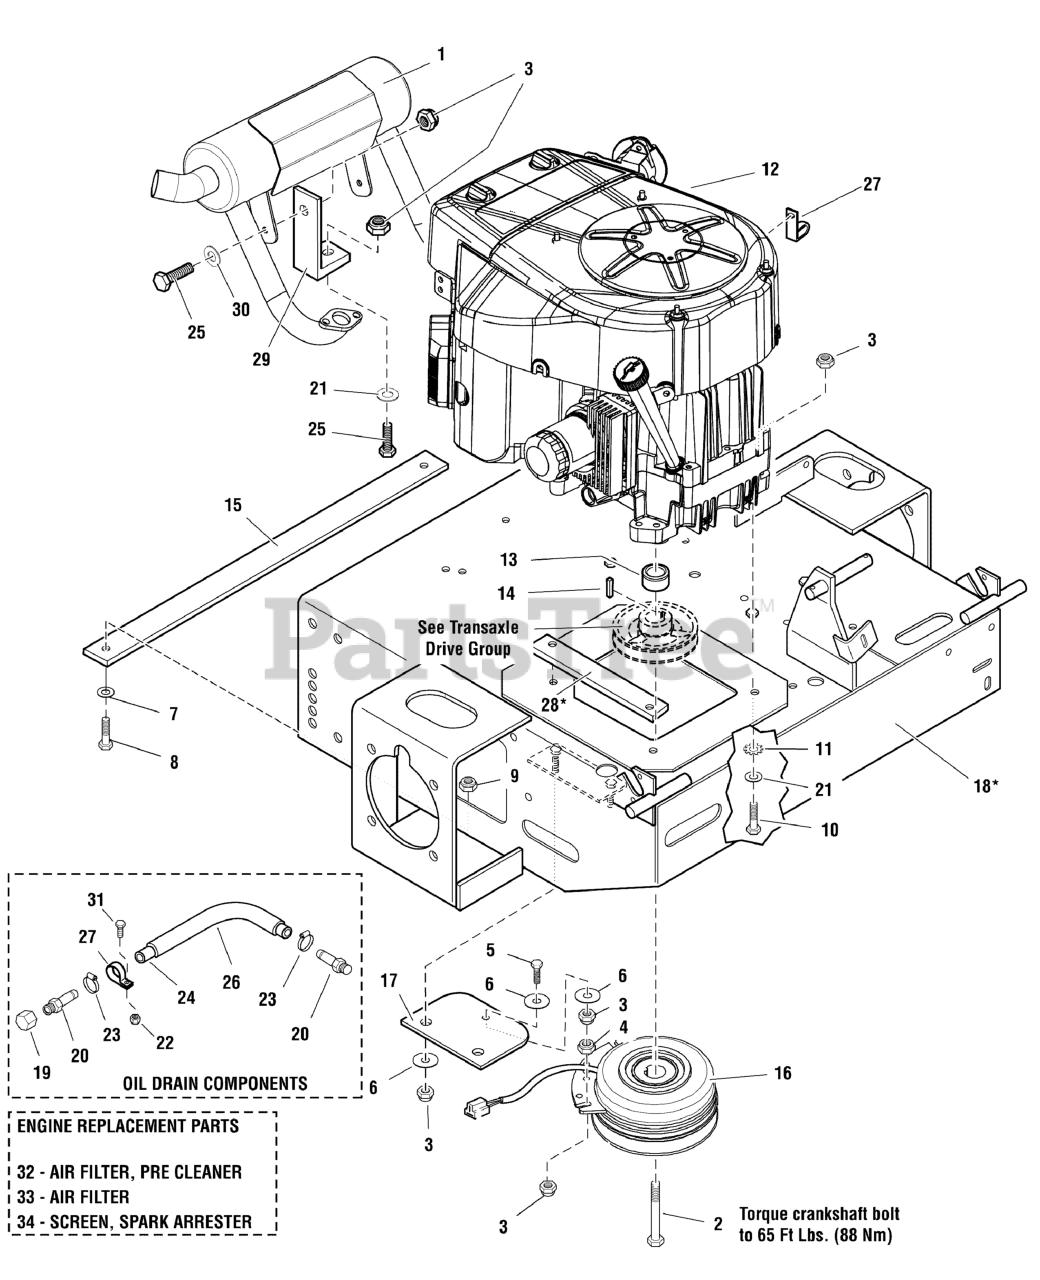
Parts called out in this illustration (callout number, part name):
1	MUFFLER, 27HP KOHLER
2	BOLT, CRANKSHAFT, 7/16"X2-1/2
3	NUT, 5/16-18 HEX NYLOCK FLANGE
4	NUT, 5/16-18 HEX SERRATED FLANGE (LARGE)
5	BOLT, 5/16-18 X 2-1/4 TFL, GD5 YZ
6	WASHER, .34 X 1.25 X 10 GA
7	WASHER, 1/2" GD9 YZ
8	BOLT, 1/2-20 X 1-1/4" GD5 CZ
9	NUT, Hex, Nylon Lock, 1/2-20
10	BOLT, 5/16-18 X 2" GD5 YZ
11	WASHER, 5/16" INT. TOOTH LOCK
12	ENGINE, 27HP KOHLER
13	SPACER, 1.13 X 1.75 X 1.347
14	KEY, 1/4" SQ. X 1.25
15	TIE BAR - RED
16	** CLUTCH, 5218-134, WARNER
17	CLUTCH ANCHOR PAD
19	CAP, 3/8" NPT
20	FITTING, 3/8NPT-1/2" HOSE. STR
21	WASHER, 5/16" SAE
22	NUT, 1/4-20 HEX SERR. FLANGE
23	CLAMP, #6 HOSE, STAINLESS
24	HOSE, 1/2" PUSH-ON, 18.50"
25	BOLT, 5/16-18 X 1"
26	WIRE LOOM, 3/4" ID, 16.00
27	CLAMP, VINYL INSULATED
28	SPACER, ENGINE BLOCK
29	BRACKET, MUFFLER - RED
30	WASHER, 5/16" GD.9 FLAT
31	BOLT, 1/4-20 X 3/4" GD5 YZ
32	PRE CLEANER, 27HP KOHLER ENGINE
33	FILTER ELEMENT, 27HP KOHLER ENGINE
34	SCREEN, SPARK ARRESTER
